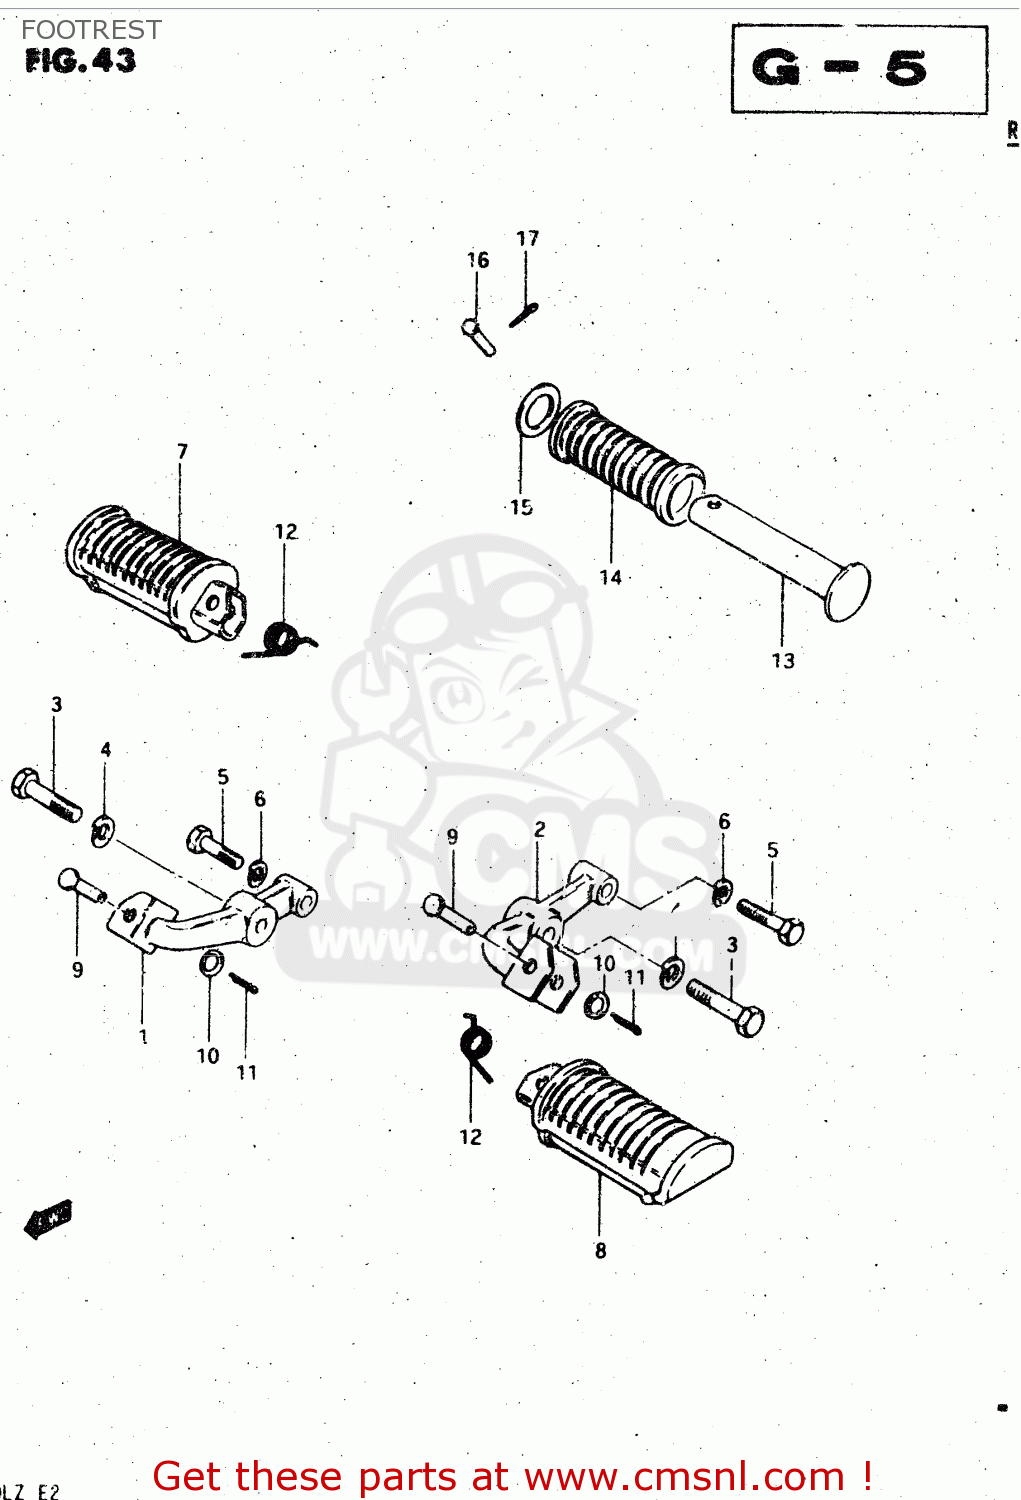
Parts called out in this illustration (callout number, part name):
1	BAR,FRONT FOOTREST,RIGHT
2	BAR,FRONT FOOTREST,LEFT
3	BOLT
4	LOCK WASHER
5	BOLT 8X40
6	LOCK WASHER
7	RUBBER,FRONT FOOTREST
8	FOOTREST
9	PIN
10	WASHER
11	PIN
12	SPRING
13	BAR,PILLION FOOTREST
14	RUBBER,PILLION FOOTREST
15	WASHER (19.5X32X2)
16	PIN
17	PIN
